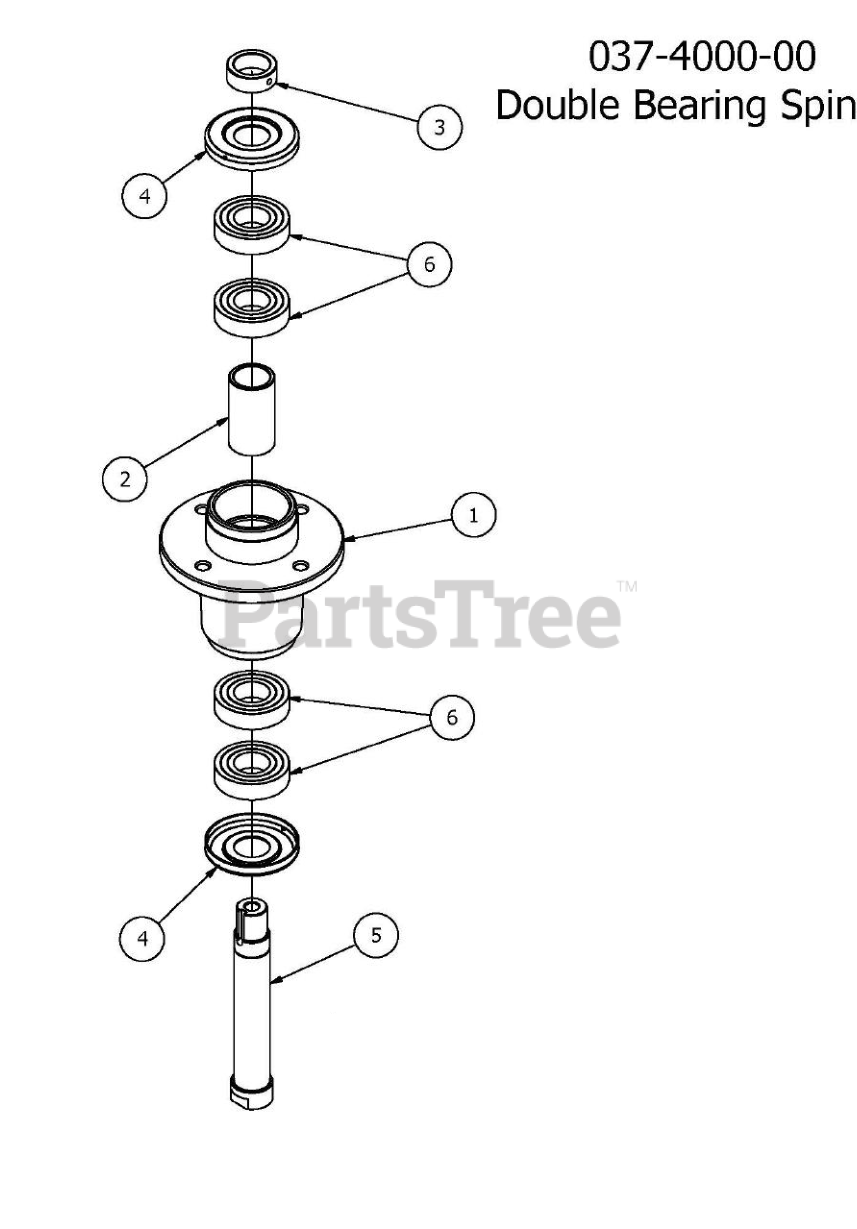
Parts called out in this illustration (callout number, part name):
1	4000 Series Spindle Housing
2	4000 Series Spindle Spacer
3	Locking Collar w/ 1/4"-20 Set Screw
4	Spindle Dust Cap
5	Spindle Shaft
6	Bearing - 6206
